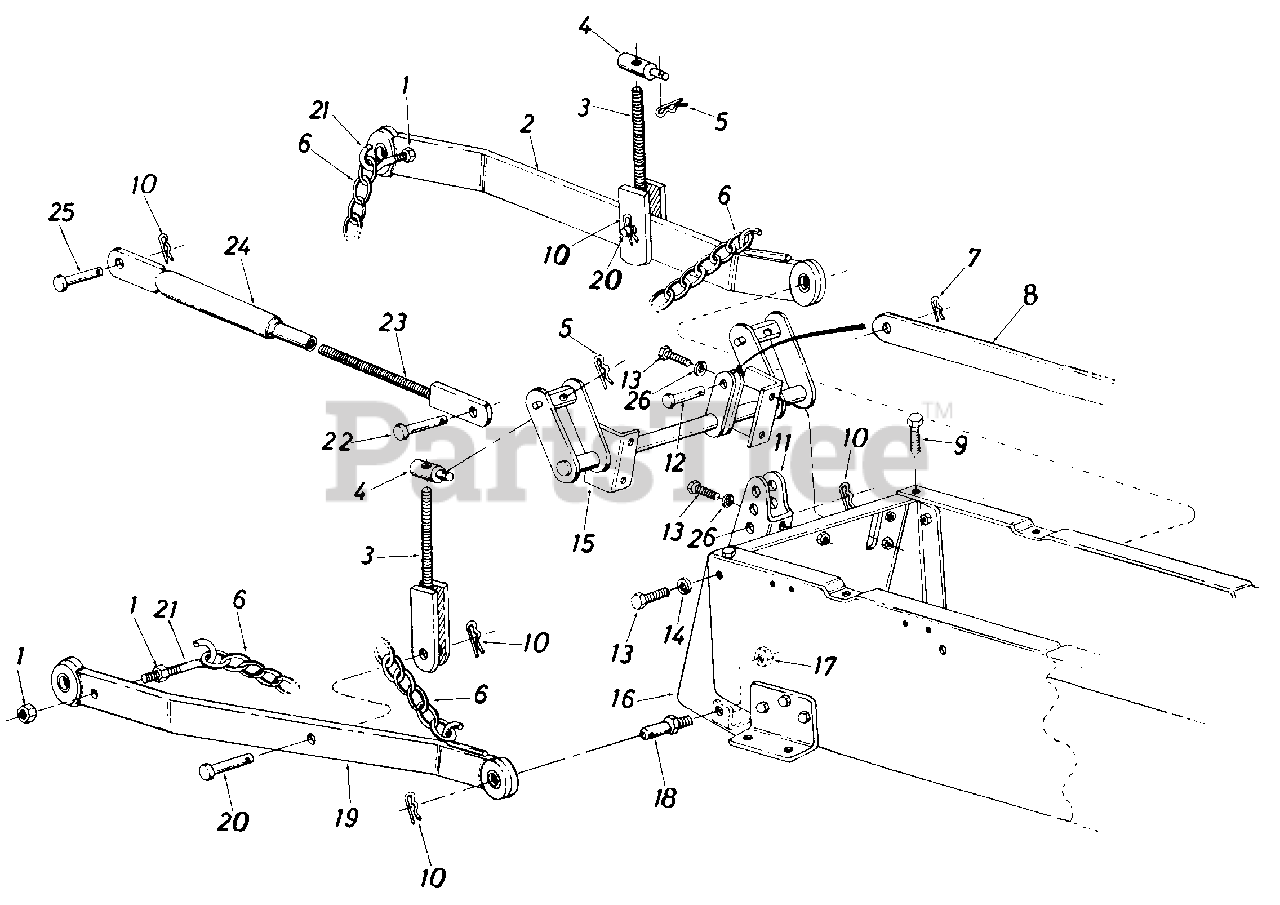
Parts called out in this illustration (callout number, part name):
1	Hex Cent. L-Nut 7/16-14 Thd.
2	Draft Bar Ass'y.-L.H.
3	Clevis Screw Ass'y.
4	Clevis Pin
5	Hitch Pin Clip
6	Chain 20 Links
7	Cotter Pin 1/8" Dia. x 1.25" Lg. *
10	Hairpin Cotter
12	Clevis Pin
13	Hex Scr. 3/8-16 x .75" Lg.
14	L-Wash. 3/8" Scr. H.D.
18	Link Clevis Pint
19	Draft Bar Ass'y.-R.H.
20	Clevis Pin .63 Dia. x 1.66" Lg.
21	Hitch Chain Hook
22	Clevis Pin .63 Dia. x 2.4" Lg.
23	Clevis Screw
25	Clevis Pin .63 Dia. x 2.4" Lg.
26	L-Wash. 3/8" Scr. H.D.
